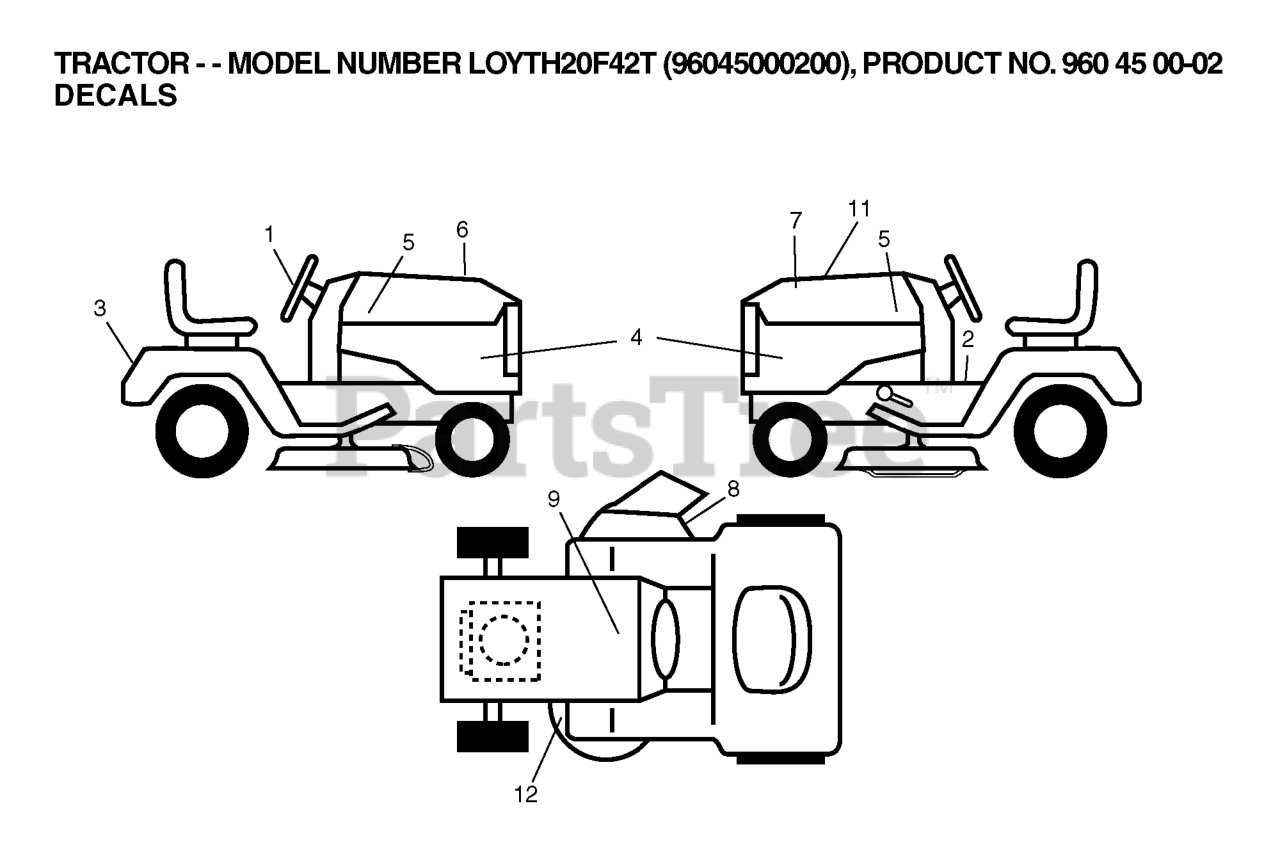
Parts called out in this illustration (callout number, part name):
1	DECAL.STEERING.HUSQ.BLUE
3	DECAL.FENDER
5	DECAL.HOOD.NAMELOGO.HUSQ
6	DECAL.HOOD.TOP.INSERT.
7	DECAL HOOD CUST. RESP.
8	DECAL DECK "B" 42"
9	DECAL BTRY SYMBOLS
12	DECAL V BELT SCHEMATIC
